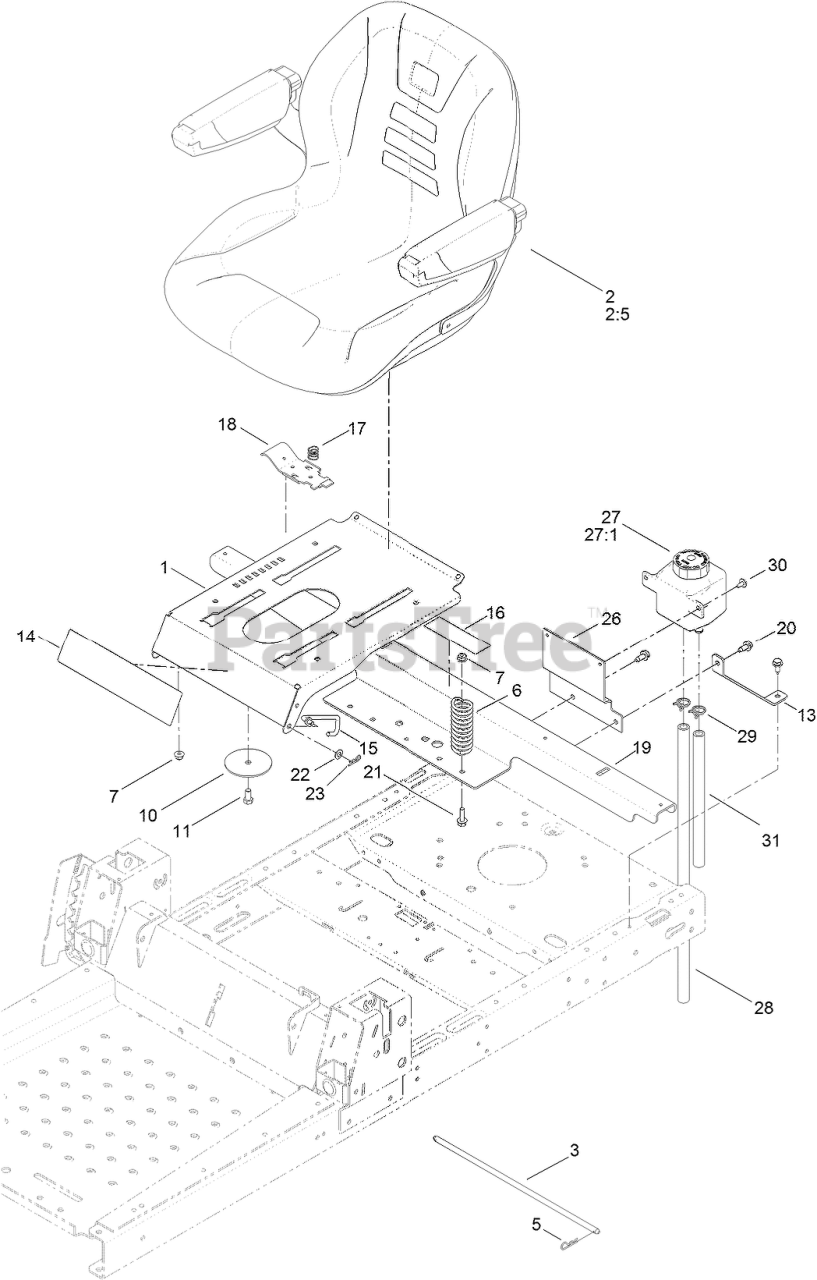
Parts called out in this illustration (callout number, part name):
1	PAN-SEAT
2	18 INCH SEAT ASM
2:5	ARMREST KIT
3	ROD-STOP
5	PIN-COTTER
6	SPRING-COMPRESSION
7	NUT-HF, NI
10	WASHER-SEAT
11	SCREW-HH
13	SUPPORT-TANK, REAR
15	STOP-SEAT
16	DECAL-SERVICE, CE
17	SPRING-COMPRESSION
18	LATCH-SEAT
19	SUPPORT-POD
20	SCREW-HWHTF
21	SCREW-HHF
22	WASHER-PLAIN
23	PIN-COTTER
26	MOUNT-TANK
27	VENT-TANK, HYD
27:1	CAP-RESERVOIR, HYD
28	HOSE-OVERFLOW
29	CLAMP-HOSE
30	SCREW-HHFTF
31	HOSE-OVERFLOW
